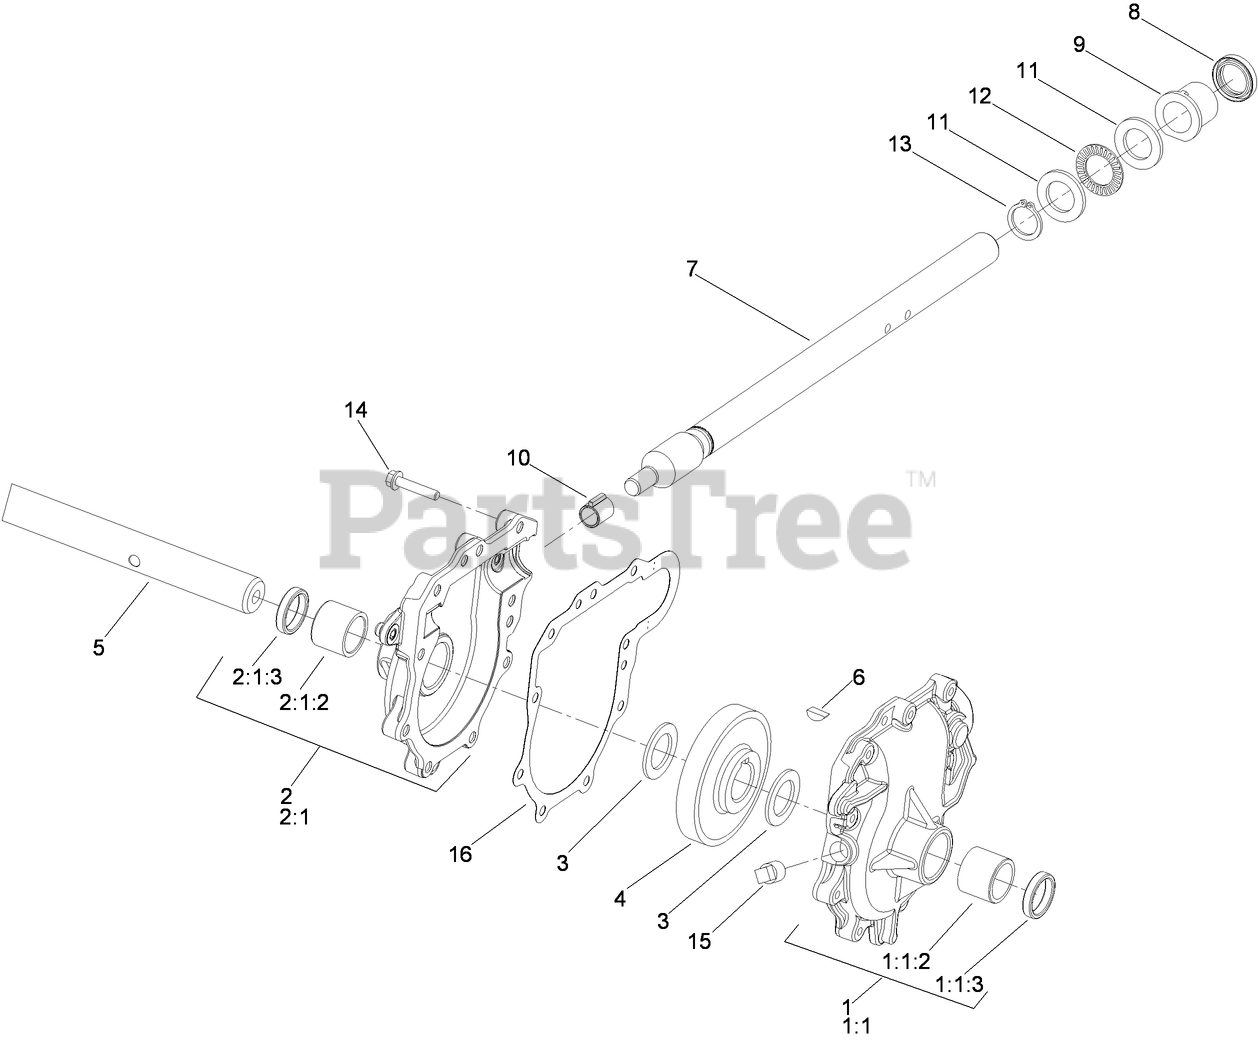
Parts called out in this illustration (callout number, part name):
1	LH AUGER GEARCASE ASM
1:1	Gearcase-Auger, LH
1:1:2	BUSHING-SLEEVE
1:1:3	SEAL-OIL
2	RH AUGER GEARCASE ASM
2:1	Loose Parts Package
2:1:2	BUSHING-SLEEVE
2:1:3	SEAL-OIL
3	WASHER-THRUST
4	GEAR-HELICAL
5	SHAFT-AUGER
6	KEY-WOODRUFF
7	SHAFT-IMPELLER
8	SEAL-OIL
9	BUSHING-INPUT
10	BUSHING-WORM
11	WASHER-THRUST
12	BEARING-THRUST
13	RING-RETAINING, EXT
14	SCREW-HWHTF
15	PLUG-PIPE, SQH
16	GASKET-GEARCASE, AUGER
